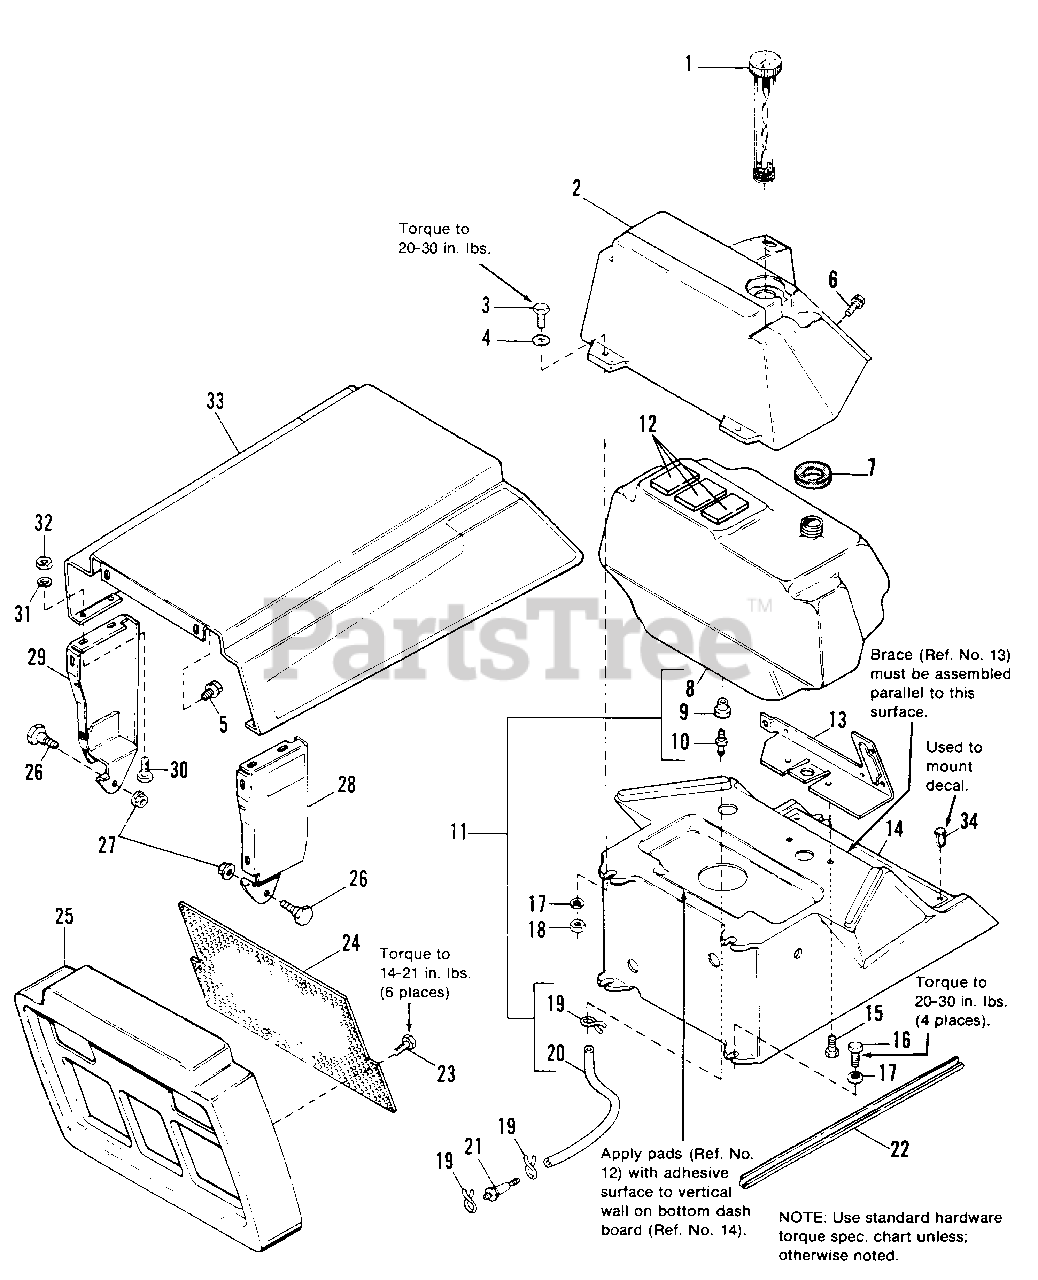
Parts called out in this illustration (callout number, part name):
1	CAP, Fuel Tank
2	DASHBOARD, Top
3	CAPSCREW, Hex, 1/4-20 x 1-1/4
4	WASHER, 1/4
5	SCREW, Plastite, 1/4 x 1
6	SCREW, Hex Washer Hd., 1/4-20 x 5/8
7	WASHER, Foam
11	TANK ASSY., Fuel
14	DASHBOARD, Bottom
15	SCREW, Taptite, 1/4-20 x 3/4
16	SCREW, Taptite, 1/4-20 x 1
17	LOCKWASHER, Dish, 1/4
18	LOCKNUT, Hex, 1/4-20
19	CLAMP, Hose
21	FILTER, Fuel
22	EDGING, Lower Dash
23	SCREW, Plastite, #10-14 x 1/2
26	BOLT, Shoulder, 5/16-18 x 7/8
27	LOCKNUT, Flange, Whiz, 5/16-18
28	PANEL ASSY., L.H.
29	PANEL ASSY., R.H.
30	CAPSCREW, Hex, 1/4-20 x 1/2
31	LOCKWASHER, 1/4
32	NUT, Hex, 1/4-20
34	CLIP, Canoe
